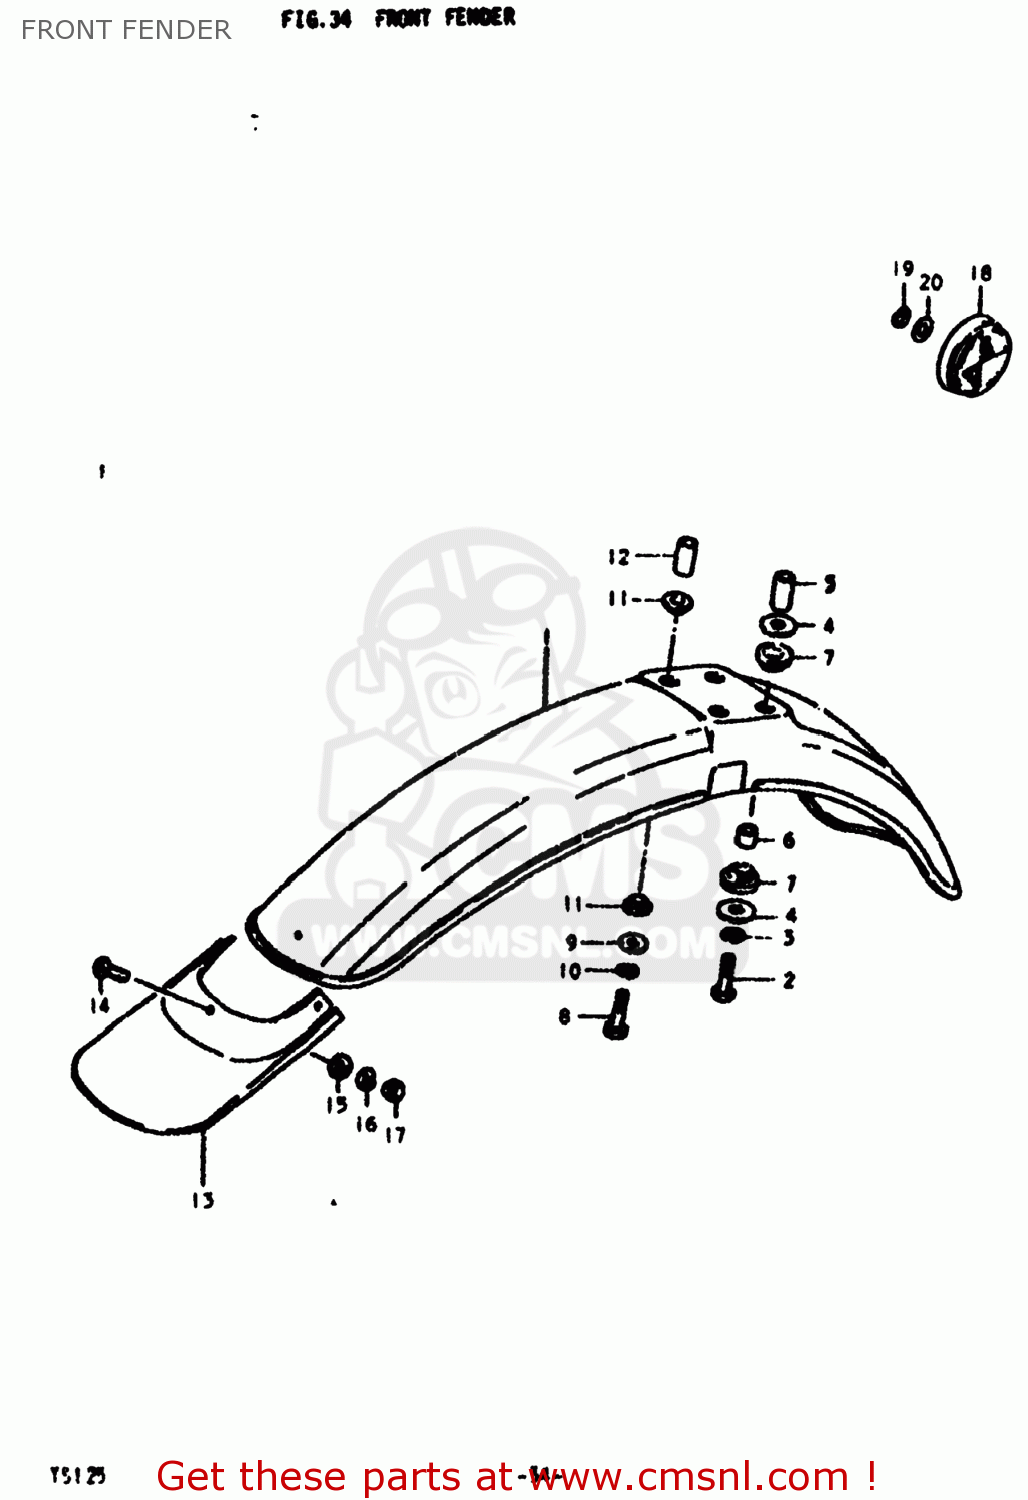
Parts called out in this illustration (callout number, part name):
1	FENDER,FRONT
2	BOLT
3	LOCK WASHER
4	WASHER (6.5X24X1.2)
5	SPACER
6	SPACER (6.5X10.5X13.5)
7	CUSHION
8	BOLT 6X40
9	WASHER
10	LOCK WASHER
11	SPACER
12	SPACER (6.8X10X20)
13	MUD FLAP,FRONT FENDER
14	SCREW
15	WASHER
16	LOCK WASHER
17	NUT
18	REFLEX REFLECTOR,FR
19	LOCK WASHER
20	WASHER
